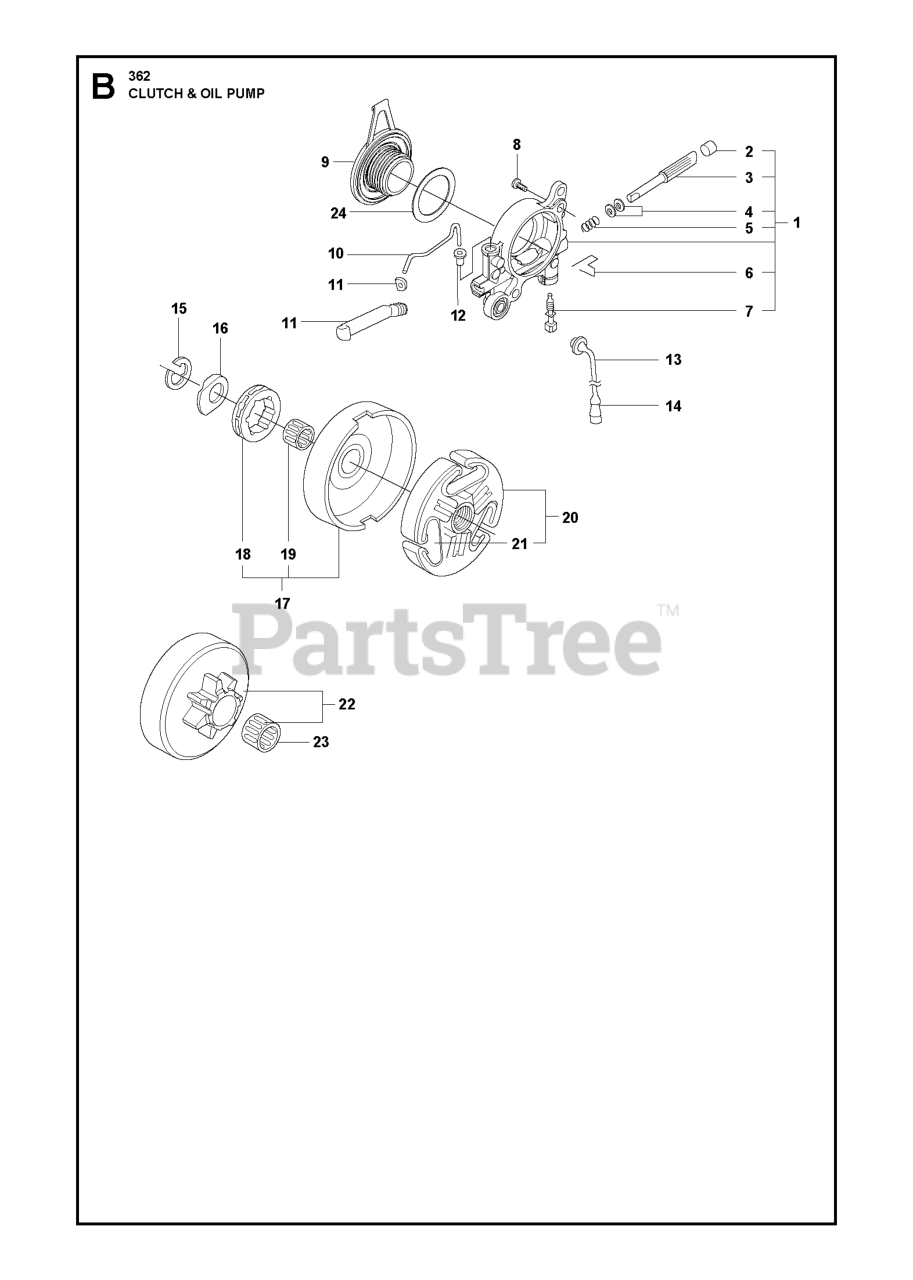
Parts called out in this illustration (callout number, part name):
1	OIL PUMP
3	PUMP PISTON
4	WASHER 6.1X9
6	SPRING CLIP
8	SCREW ITXSCM M5X16 T27 12.9 T
9	PUMP PINION
11	OIL PRESSURE HOSE
11	GROMMET
14	OIL SCREEN
15	RETAINING RING
17	CLUTCH DRUM ASSY
18	68210 RIMSPROCKET
18	22273 Sprocket 3/8"x8T
19	CLUTCH DRUM BEARING
20	CLUTCH ASSY M14X1.25-6H
22	CLUTCH DRUM
23	CLUTCH DRUM BEARING
